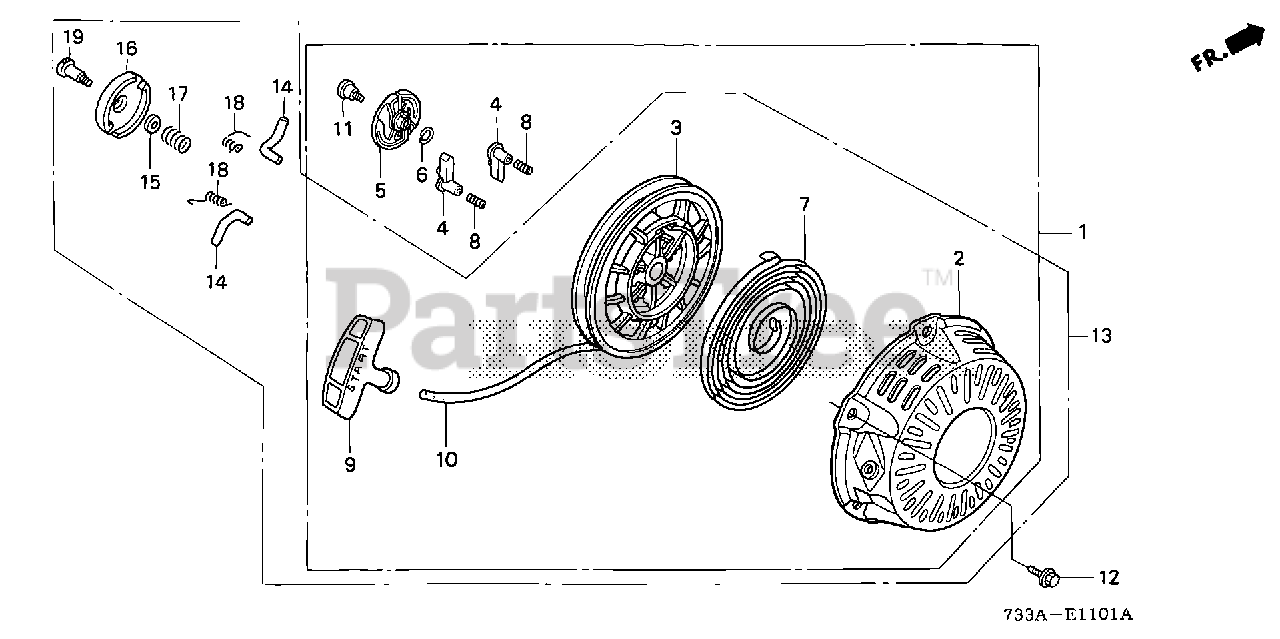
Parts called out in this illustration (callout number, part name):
1	STARTER ASSY., RECOIL *R280* (POWER RED)
2	CASE, RECOIL STARTER *R280* (POWER RED)
2	CASE, RECOIL STARTER *R8* (BRIGHT RED)
3	REEL, RECOIL STARTER (NATURAL)
4	RATCHET, STARTER
5	GUIDE, RATCHET
6	SPRING, FRICTION
7	SPRING, RECOIL STARTER
8	SPRING, RETURN
9	KNOB, RECOIL STARTER
10	ROPE, RECOIL STARTER
11	SCREW, SETTING
12	BOLT, FLANGE (6X8)
